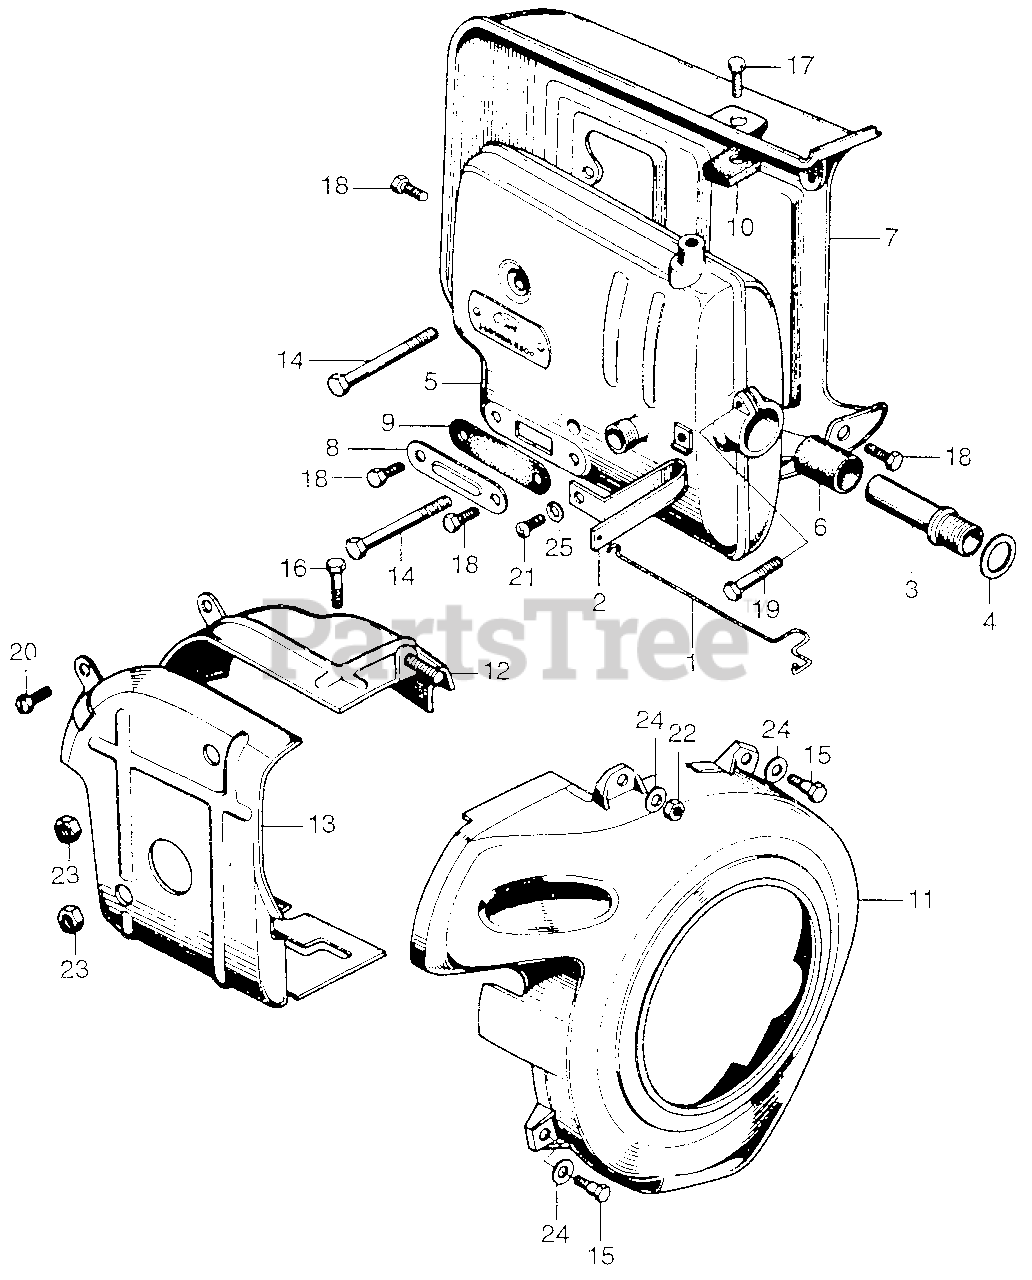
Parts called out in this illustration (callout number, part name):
1	ROD, CHOKE
2	BIMETAL, AUTO CHOKE
3	PIPE, EX.
4	GASKET, EX. PIPE
5	MUFFLER (NOT AVAILABLE)
6	SEAL, EX. PIPE (NOT AVAILABLE)
7	PROTECTOR, MUFFLER
8	LID, MUFFLER
9	GASKET, MUFFLER LID
10	STOPPER, PROTECTOR
11	COVER, FAN (NOT AVAILABLE)
12	VANE A, GUIDE
13	VANE B, GUIDE
14	BOLT, MUFFLER SET
15	BOLT, FAN COVER (NOT AVAILABLE)
16	BOLT, HEX. (5X8)
17	BOLT, HEX. (5X14)
18	BOLT, HEX. (5X10)
19	BOLT, HEX. (5X20)
20	BOLT, SLOT (5X8)
21	SCREW, PAN (5X10)
22	NUT, HEX. (5MM)
23	NUT, HEX. (6MM)
24	WASHER, PLAIN (5MM)
25	WASHER, SPRING (5MM)
